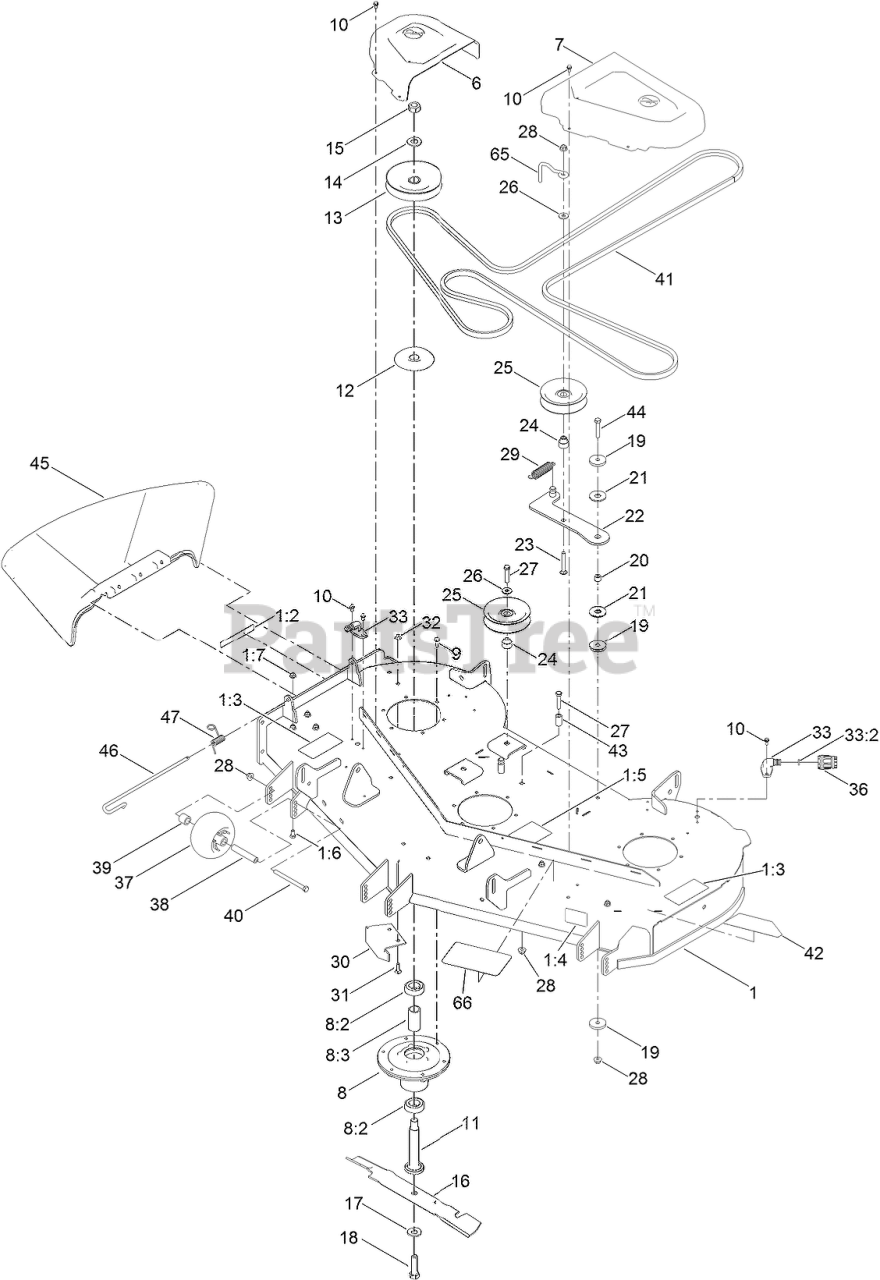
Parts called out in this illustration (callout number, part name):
1	DECK ASM
1:2	DECAL-DANGER
1:3	DECAL-DANGER, DECK
1:4	DECAL-SCALP, ANTI
1:5	DECAL-ROUTING, BELT
1:6	SCREW-HH
1:7	NUT-HF, NI
6	COVER-BELT, RH
7	COVER-BELT, LH
8	SPINDLE ASM
8:2	BEARING-BALL
8:3	SPACER-BEARING
9	SCREW-TAPTITE
10	SCREW-HWH
11	SHAFT-SPINDLE
12	SHIELD-BEARING
13	PULLEY
14	WASHER
15	NUT-HEX
16	BLADE-HI FLO
17	WASHER-BELLEVILLE
18	SCREW-BLADE
19	WASHER-PLAIN
20	BUSHING-LEVER, LIFT
21	WASHER-FRICTION, COMPOSITE
22	ARM-IDLER
23	SCREW-CARR
24	BUSHING-IDLER
25	PULLEY-IDLER, FLAT
26	WASHER-HARDENED
27	SCREW-HH
28	NUT-HF, NI
29	SPRING-EXTENSION
30	BAFFLE-CUTOFF
31	SCREW-CARR
32	NUT-HF, NI
33	FITTING-WASHOUT
33:2	O-RING
36	CONNECTOR-HOSE
37	ROLLER-SCALP, ANTI
38	TUBE-SPANNER
39	SPACER-AXLE, REAR
40	SCREW-HH
41	V-BELT
43	SPACER
44	SCREW-HH
45	DEFLECTOR-DISCHARGE
46	PIN-CHUTE
47	SPRING-TORSION
65	GUIDE-BELT, IDLER
66	TREAD-STEP
